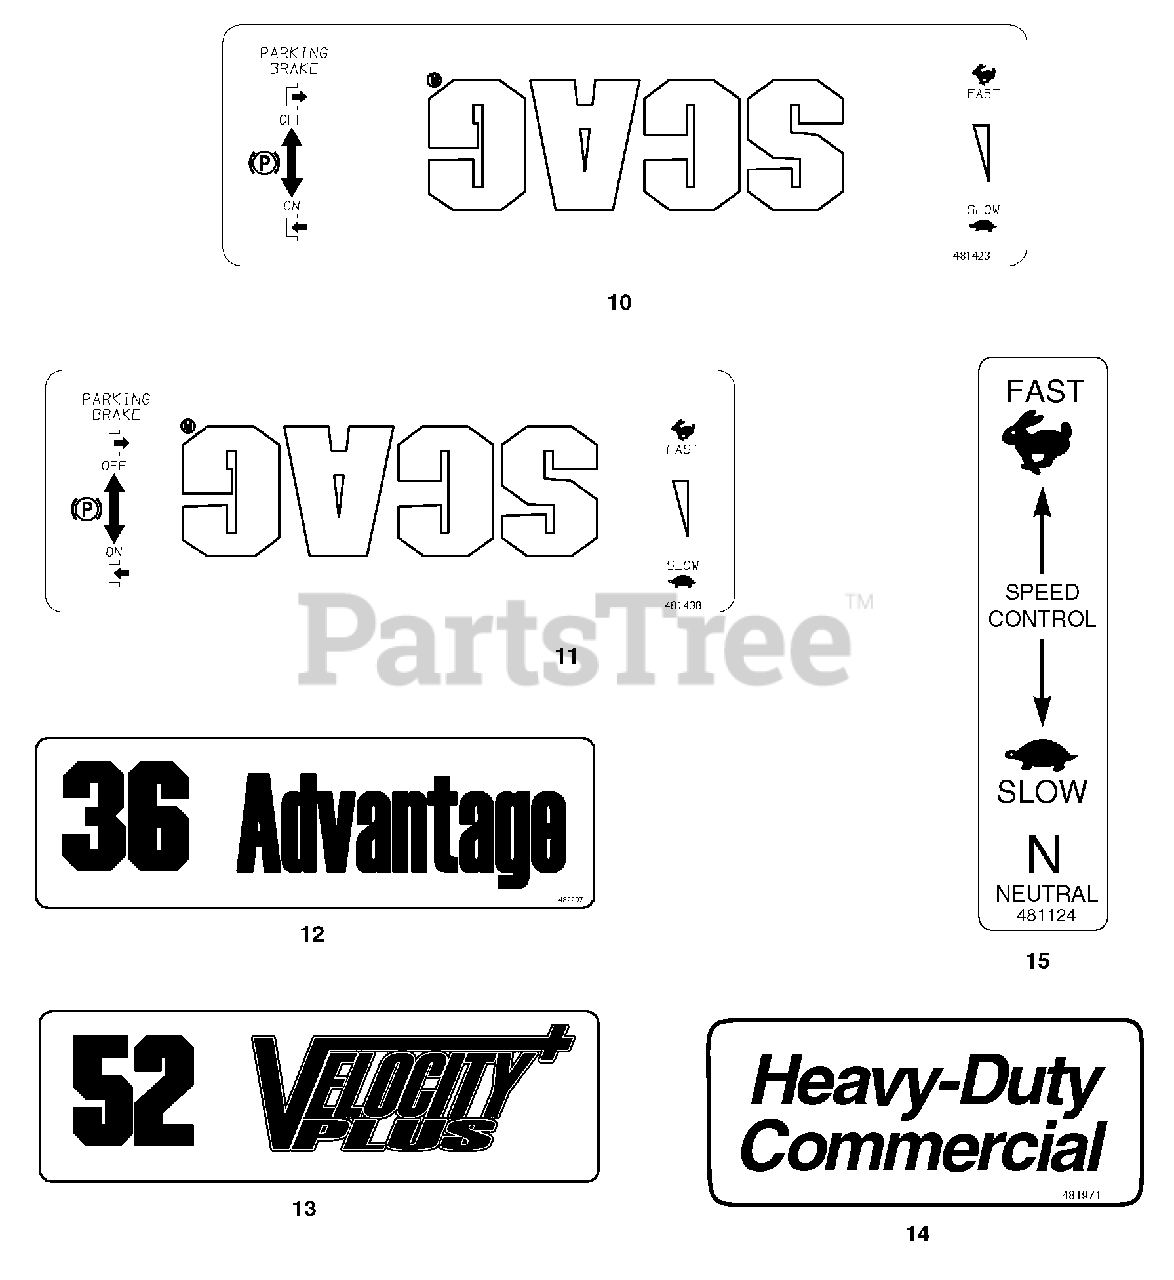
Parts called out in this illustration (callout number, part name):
10	Decal, Instrument Panel - Front (SWZ-18FS & SWZ-22FSE only)
11	Decal, Instrument Panel - Front
12	Decal, 36 Advantage
13	Decal, 48 Velocity Plus
13	Decal, 52 Velocity Plus
13	Decal, 61 Velocity Plis
14	Decal, Heavy Duty Commercial
15	Decal, Speed Control
